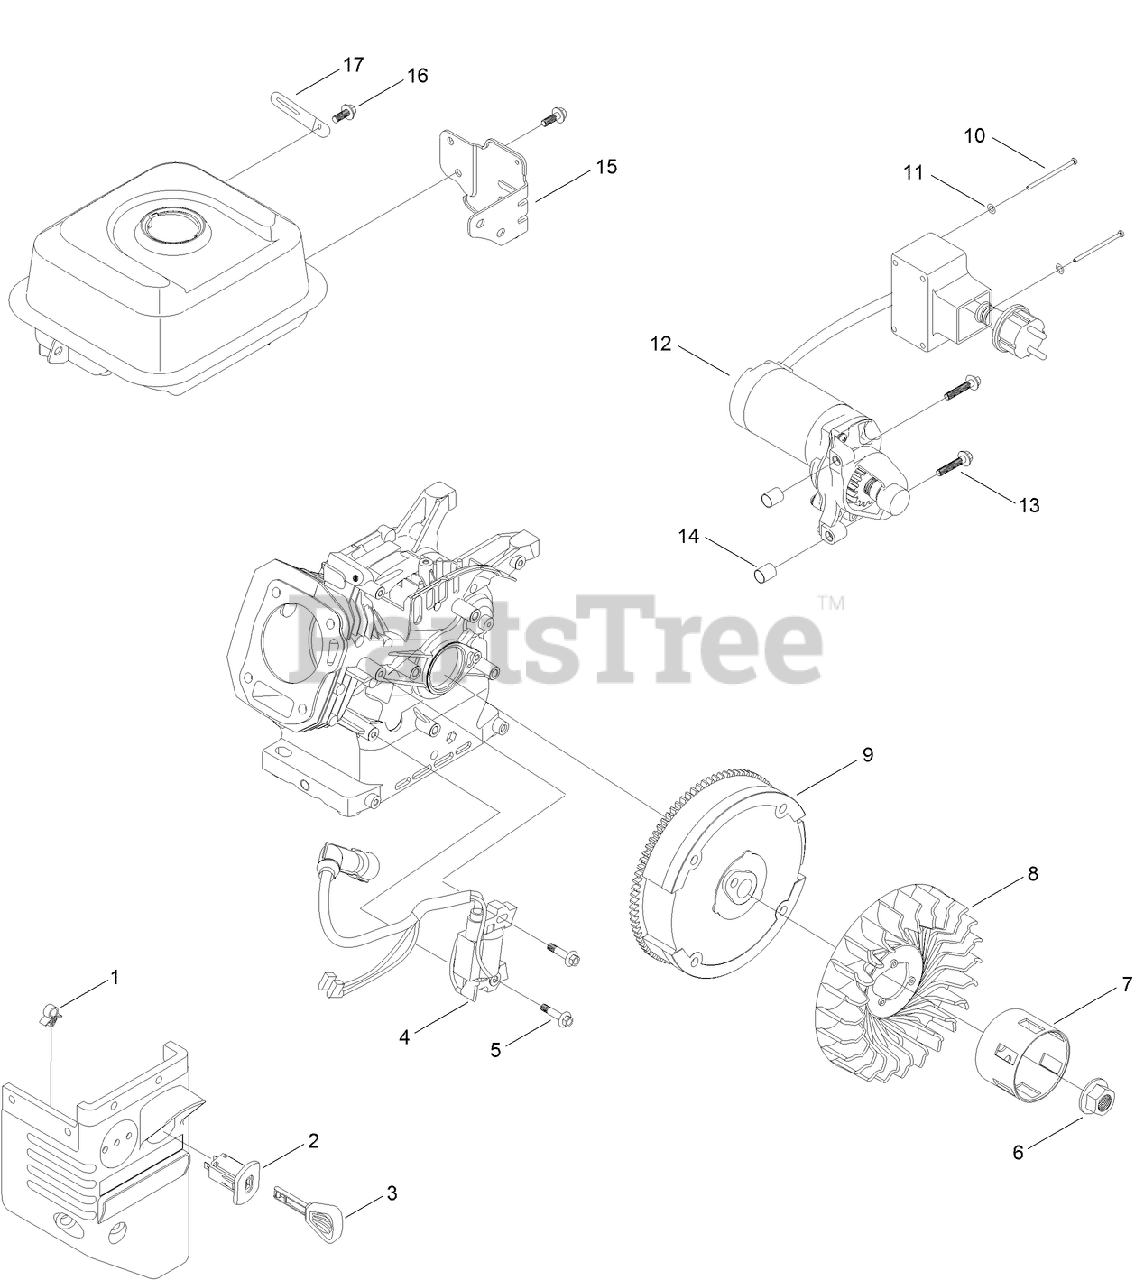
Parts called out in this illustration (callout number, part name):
2	SWITCH-KEY
5	SCREW-HHF
6	NUT-FLANGE
7	CUP-STARTER
9	FLYWHEEL
10	SCREW-BHP
11	WASHER-PLAIN
13	SCREW-HHF
14	PIN-DOWEL
15	BRACKET-BOX, SWITCH
16	SCREW-HHF
17	CLIP-HARNESS, WIRE
